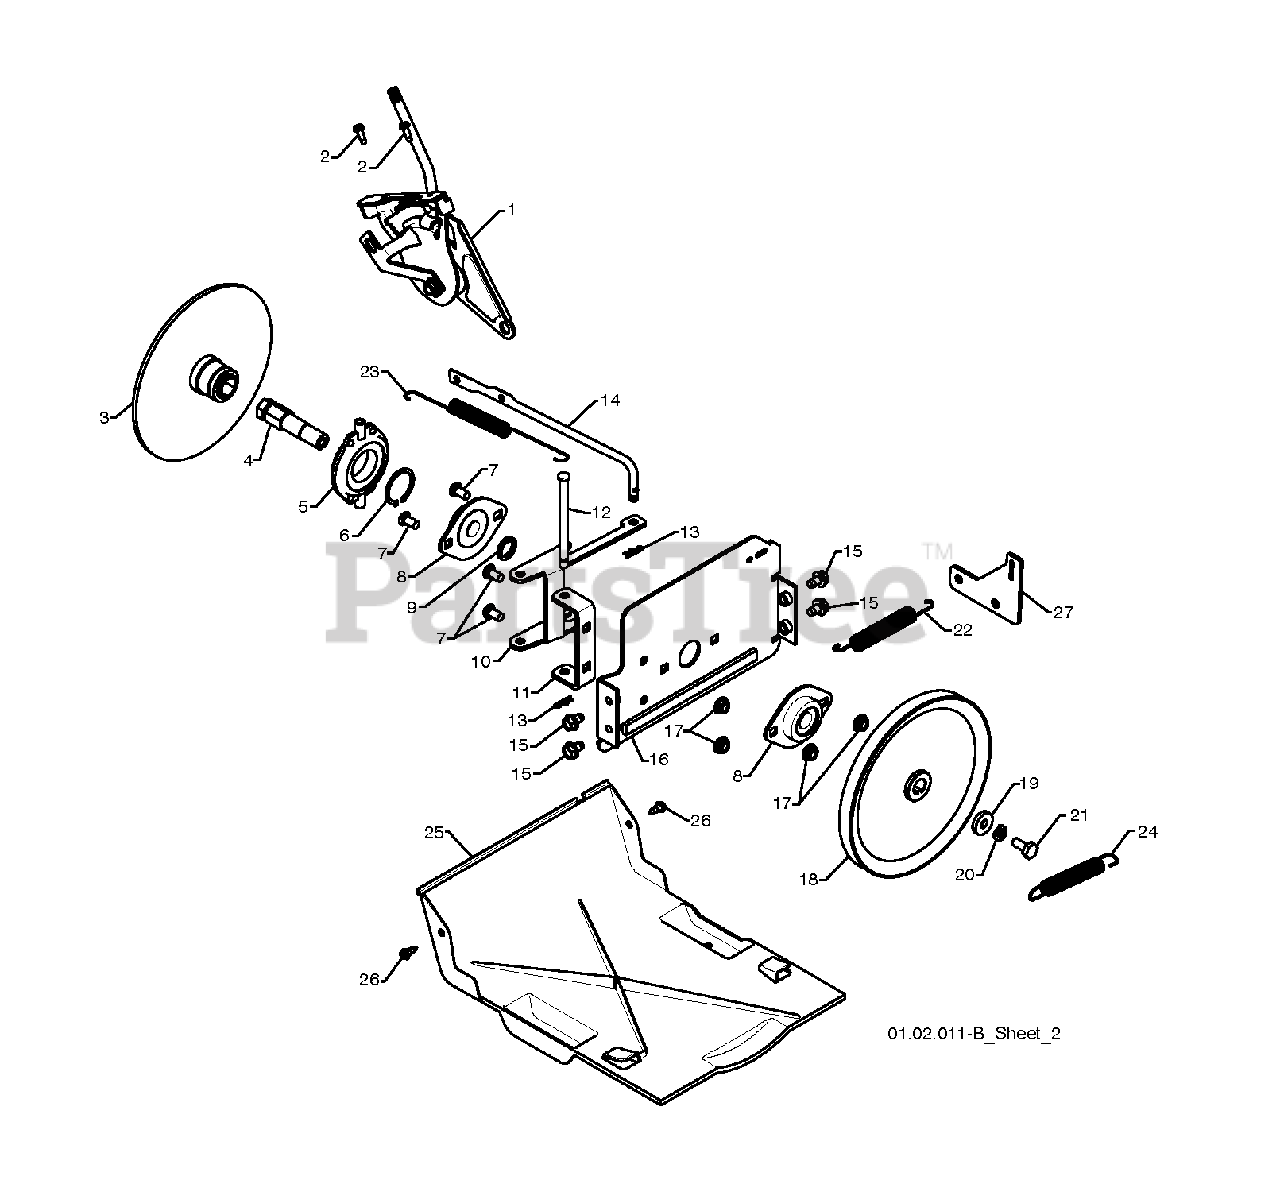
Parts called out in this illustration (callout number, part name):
1	HEAD ASSY SPEED
2	SCREW #10-24 X 5/8
3	DRIVE PLATE WELDMENT
4	SHAFT.HEX.SHORT
5	TRUNNION BEARING ASSY
6	RETAINING RING
7	BOLT
8	BEARING FLANGE
9	SPACER, BEARING
10	LEVER.SHIFTER.PLATE.BLACK
11	BRACKET.SHIFTER.SUPPORT.BLACK
12	PIN, PIVOT LEVER
13	RETAINER CLIP PM
14	ROD.CLUTCH.YELLOW.ZINC(VT)
16	PLATE.DRIVE.MOUNT.BLACK
17	NUT.FLANGE.5/16
18	PULLEY.TRACTION.7.75
19	WASHER, FLAT
20	LOCKWASHER
22	SPRING.TRACTION.IDLER
23	SPRING.RETURN
24	SPRING, BRAKE
25	PAN.BOTTOM.PLASTIC
26	SCREW, HEX HEAD, TAPPING
27	BRACKET.TRACTION.SPRIN
